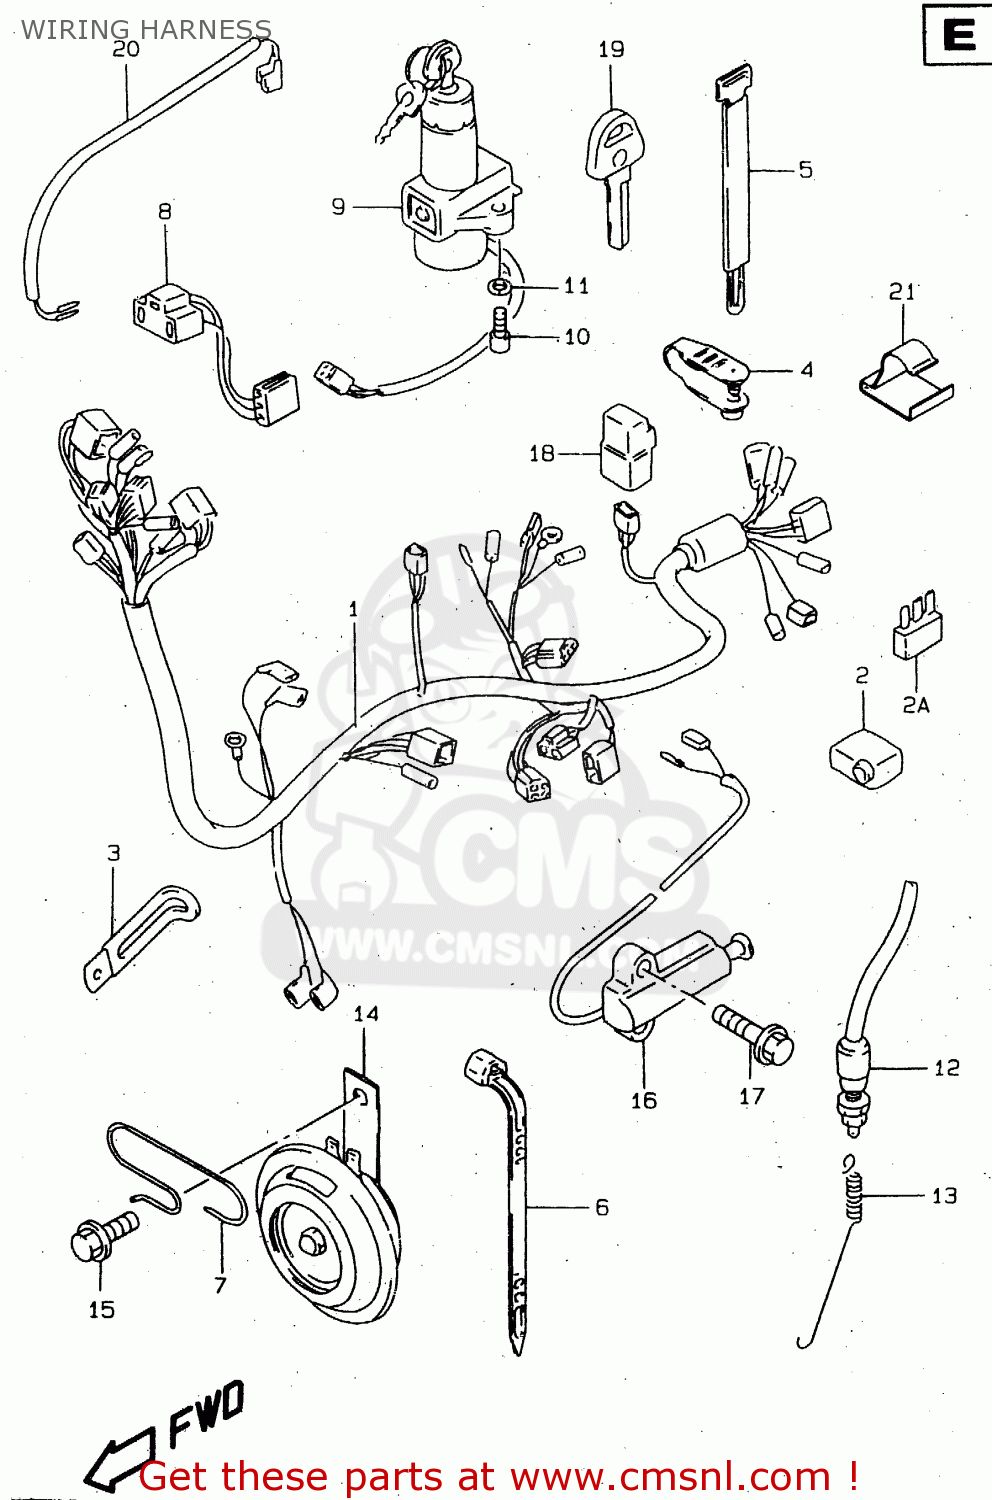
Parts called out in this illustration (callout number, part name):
1	HARNESS,WIRING
2	CAP,BATTERY PLUS TERMINAL
2A	DIODE(STANLEY DE8804)
3	CLAMP(L:65 T:0.8)
4	CLAMP,L:88
5	CLAMP(L:235)
6	CLAMP L:165
7	CLAMP,WIRING HARNESS
8	LEAD WIRE,HEADLAMP
9	SWITCH ASSY,IGNITION
10	BOLT
11	WASHER,LOCK
12	SWITCH ASSY,STOP LAMP
13	SPRING
14	HORN ASSY
15	BOLT
16	SWITCH ASSY,SIDE STAND
17	BOLT
18	RELAY ASSY
19	KEY,BLANK
20	WIRE,STOP LAMP SWITCH LEAD
